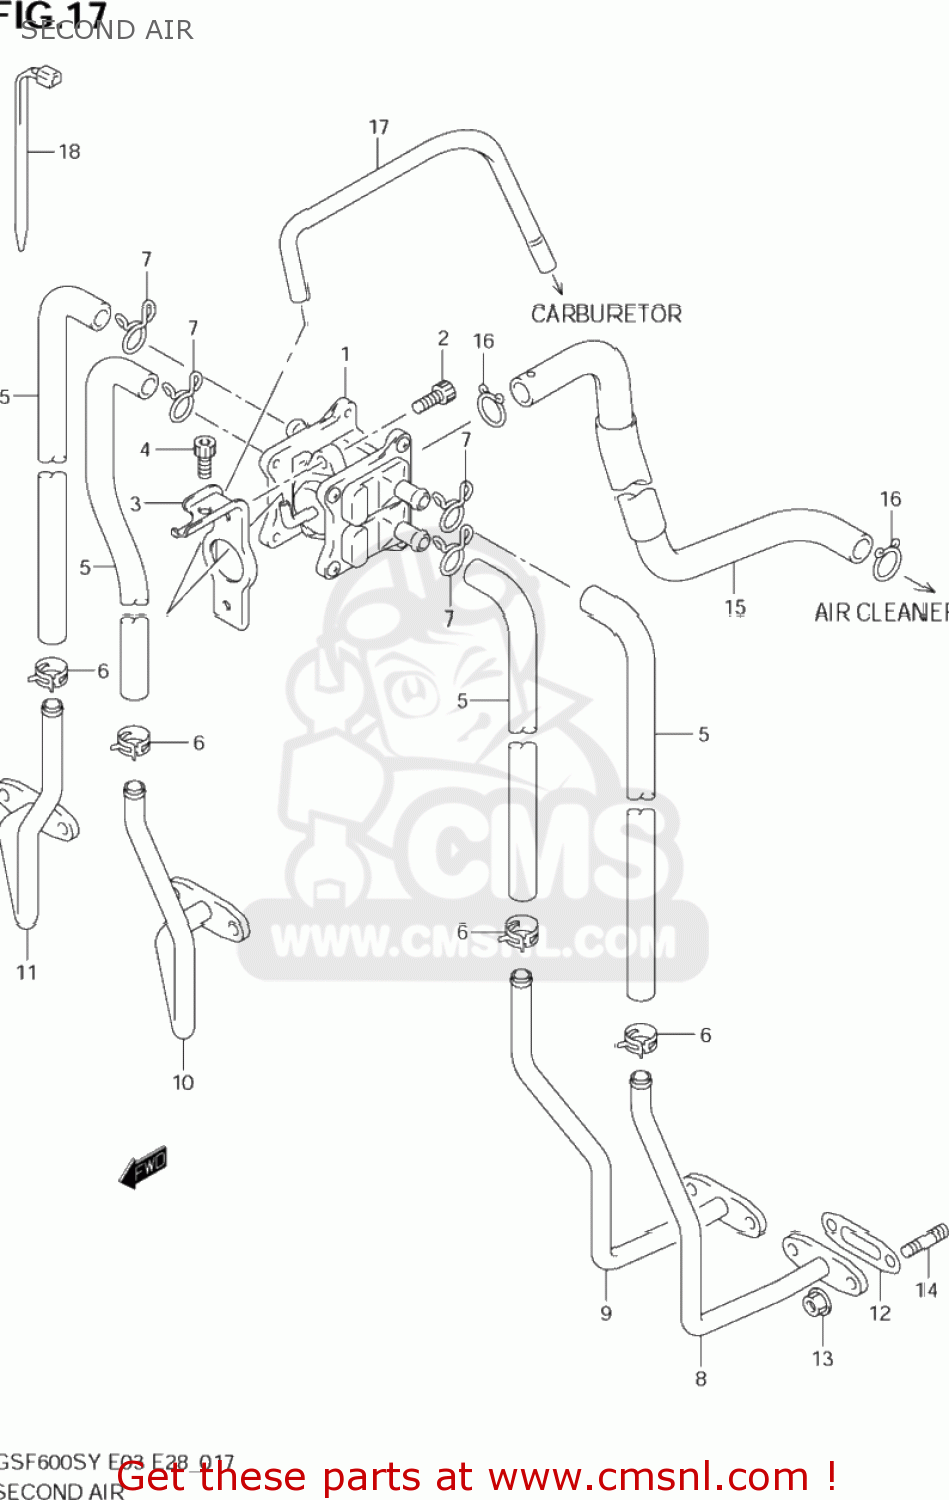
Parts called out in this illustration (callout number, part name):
1	VALVE ASSY,2ND AIR
2	BOLT,OIL FILLE
3	BRACKET,2ND AIR
4	BOLT
5	HOSE,2ND AIR VALVE NO.1
6	CLIP
7	CLIP
8	PIPE,2ND AIR NO.1
9	PIPE,2ND AIR NO.2
10	PIPE,2ND AIR NO.3
11	PIPE,2ND AIR NO.4
12	GASKET,2ND AIR PIPE (NAS)
13	NUT
14	STUD BOLT
15	HOSE,2ND AIR CLEANER
16	CLIP
17	HOSE(4X7X600)
18	CLAMP(L:165)
